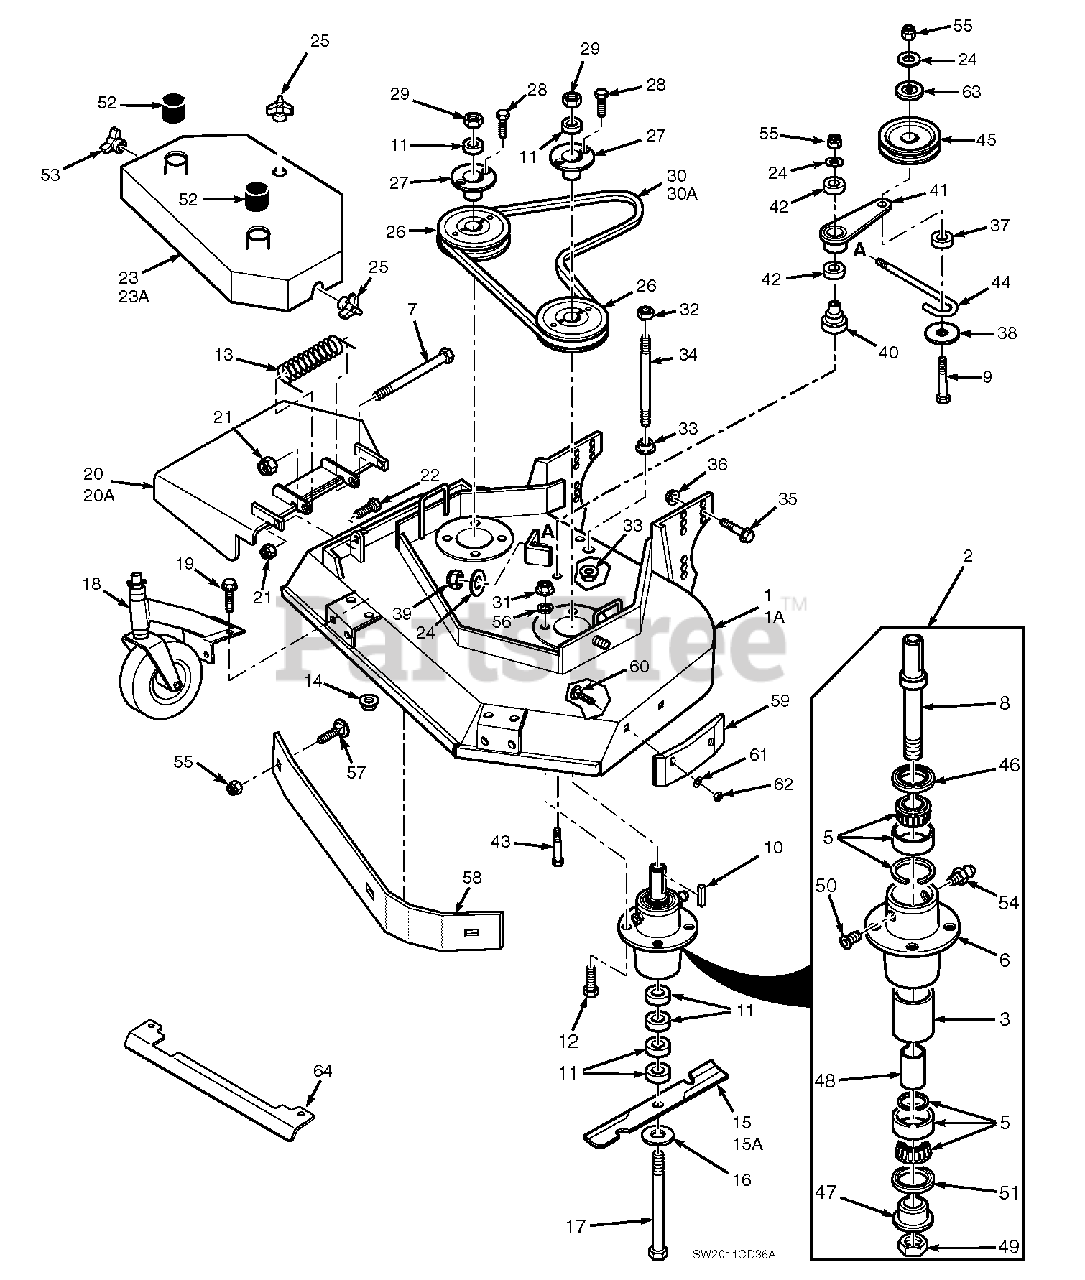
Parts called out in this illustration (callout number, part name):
1	Cutter Deck w/Decals
1A	Cutter Deck w/Decals
2	Cutter Spindle Assembly
3	Spacer, Outside
5	Bearing, Tapered
6	Spindle Housing
7	Bolt, 5/16-18 x 4-3/4"
8	Spindle Shaft
9	Bolt, 3/8-16 x 3-3/4" Hex Head
10	Key, 1/4 x 1/4 x 2"
11	Spacer, Cutter Blade - Small
12	Bolt, 5/16-18 x 1-1/2" Hex Head Grade 8
13	Spring, Chute Return
14	Nut 5/16-18 Serrated Flange
15	Cutter Blade, 16-1/2"
15	Cutter Blade, 18"
15A	Cutter Blade 16-1/2 Hi-Lift
15A	Cutter Blade, 18 Hi-Lift
16	Flatwasher, 5/8 W
17	Hex Hd. Bolt, 5/8-11 x 9-1/2"
18	Caster Assembly
19	Cpscrw,5/16-18 x 3/4" Ser.Flg. Hex Head
20	Discharge Chute
20A	Discharge Chute
21	Hex Nut, 5/16-18 Elastic Stop
22	Hex Hd Bolt, 5/16-18 x 1"
23	Belt Cover Assy
23A	Belt Cover Assy
24	Flat Washer, 3/8" Special
25	Wing Nut, 3/8-16
26	Pulley
27	Tapered Hub
28	Hex Hd. Bolt, 1/4-20 x 1"
29	Hex Nut, 5/8-11
30	Belt, Blade Drive
30A	Belt, Blade Drive
31	Elastic Stop Nut, 5/16-18 Grade 8
32	Hex Nut, 3/8-16 Center Locknut
33	Nut, 3/8-16 Serrated Flange
34	Support, Belt Cover
35	Cpscrw, 1/2-13 x 1"Ser.Flg. HH
36	Nut, 1/2-13 Spiralock
37	Spacer, J-Hook
38	Flatwasher, 3/8 x 1-1/2 x 16 GA
39	Elastic Stop Nut, 3/8-16
40	Idler Pivot
41	Idler Arm Assy.
42	Bearing
43	Cpscrw, 3/8-16 x 3-1/4" Hex Head
44	J-Hook
45	Idler Pulley, Belt Clutch
46	Seal, Cutter Spindle
47	Spindle Bushing
48	Spacer, Inside
49	Nut,1.06-18
50	Relief Fitting, Cutter Spindle
51	Seal, Cutter Spindle
52	Spindle Shield
53	Wing Nut, 3/8-16 (Small) RH side
54	Grease Fitting
55	Nut, Hex Elastic Stop 3/8-16
56	Lock Washer, 5/16"
57	Bolt, Carriage 3/8-16 x 1"
58	Baffle Weldment
59	Pad, Deck Wear
60	Bolt, Carriage 5/16-18 x 3/4"
61	Flatwasher, 5/16"
62	Hex Nut, 5/16-18 Center Locknut
63	Dust Shield
64	Heatshield
